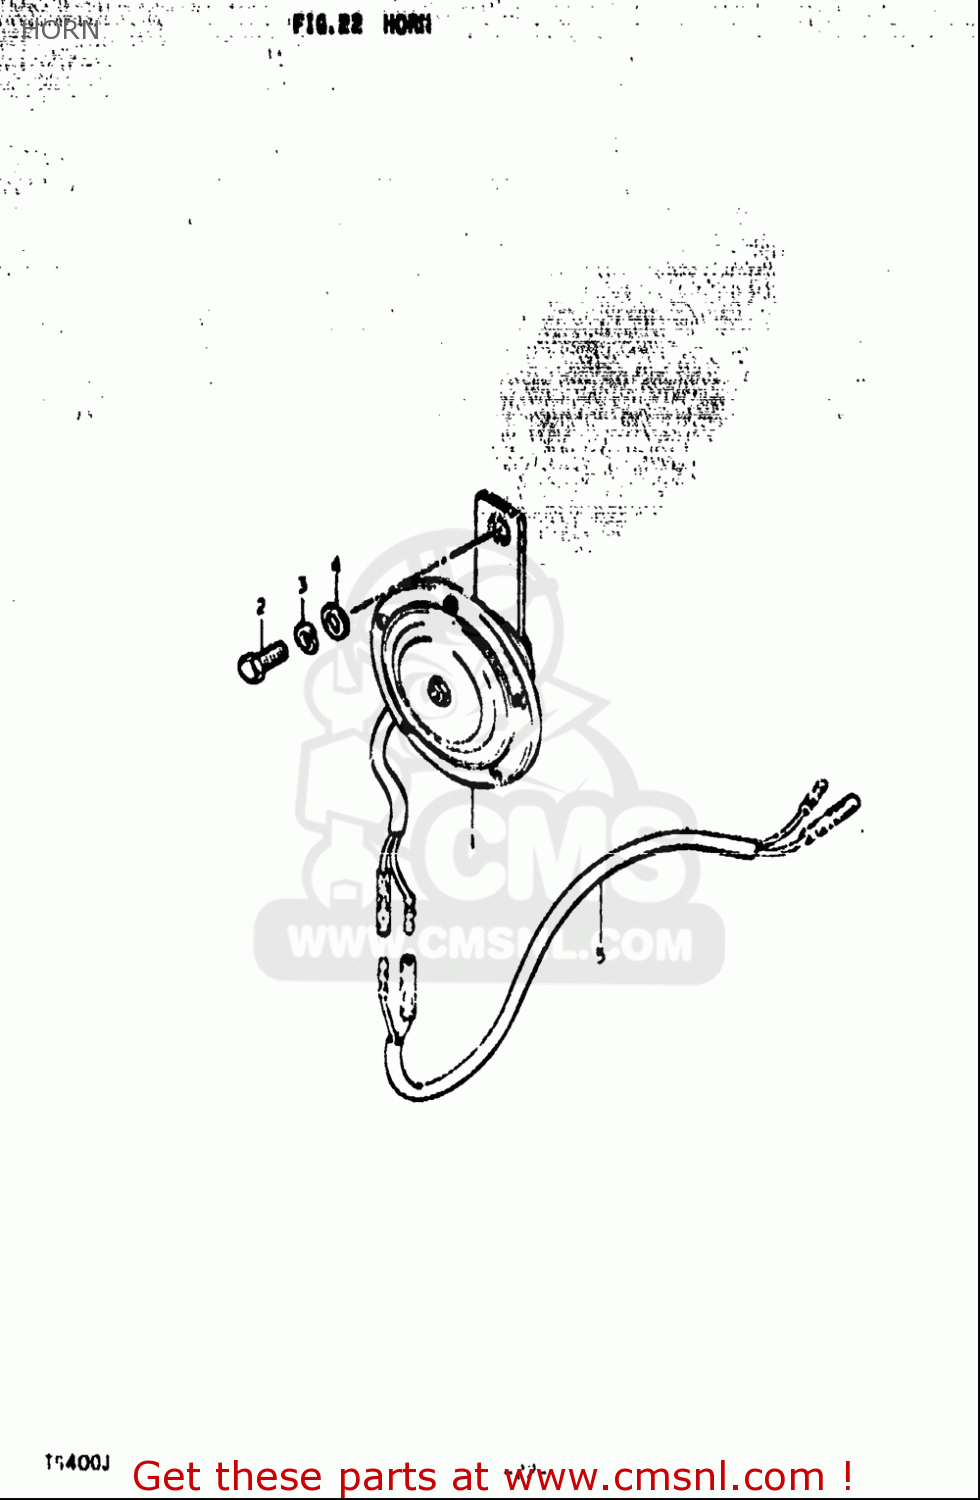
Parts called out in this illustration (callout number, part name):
2	BOLT
3	WASHER,LOCK
4	WASHER
